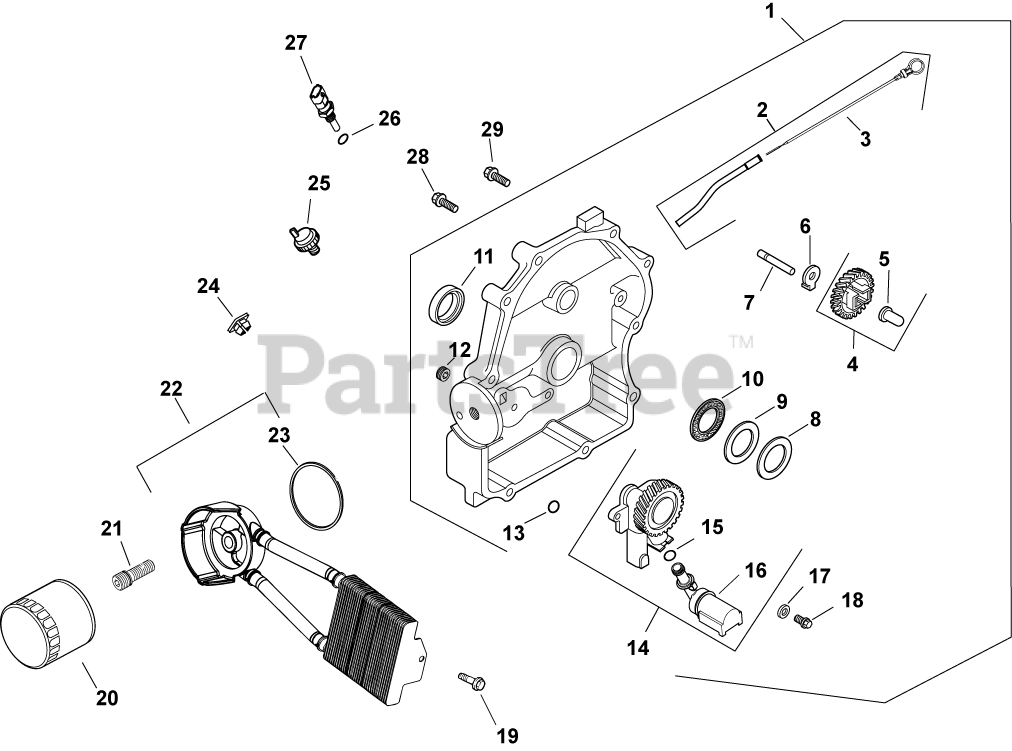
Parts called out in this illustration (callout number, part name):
1	KIT, CLOSURE PLATE USE 24 009 230-S
2	KIT, DIPSTICK/DIPSTICK TUBES
4	KIT, GOVERNOR GEAR W/PIN
5	PIN, GOVERNOR REGULATING
6	TAB, LOCKING
7	SHAFT, GOVERNOR GEAR
8	SHIM, THRUST (GREEN .875MM) - DISCONTINUED
9	WASHER, THRUST (1MM)
10	BEARING, THRUST
11	SEAL, OIL (KM)-USE 25 032 06-S
12	PLUG, CTSK PIPE 1/8"
14	PUMP ASSEMBLY, OIL-USE 24 393 53-S
15	O-RING, OIL PICK-UP
16	PICK-UP, OIL
17	WASHER, FLAT 6 MM
18	SCREW,FLG THD FRM M6X1.0X25-(#25086395S)
19	SCREW, TAP M6X1.7X18
20	OIL FILTER
21	NIPPLE, OIL FILTER
22	COOLER, OIL-USE 24 594 37-S
23	O-RING, OIL COOLER
24	NUT, PLASTIC (KM)-USE 25 100 37-S
25	SWITCH, PRESSURE (CLOSED)-USE 25 099 27-
26	O-RING (.5" DIA)
27	SENSOR, TEMPERATURE
28	SCREW, HEX FLANGE -USE 24 086 17-S
29	SCREW, FLG M8X1.25X45
2442204-S	SHIM, THRUST (BLUE .5MM)
2442205-S	SHIM, THRUST (BLACK .686MM)
24755134-S	KIT, WIRING HARNESS (EFI)
